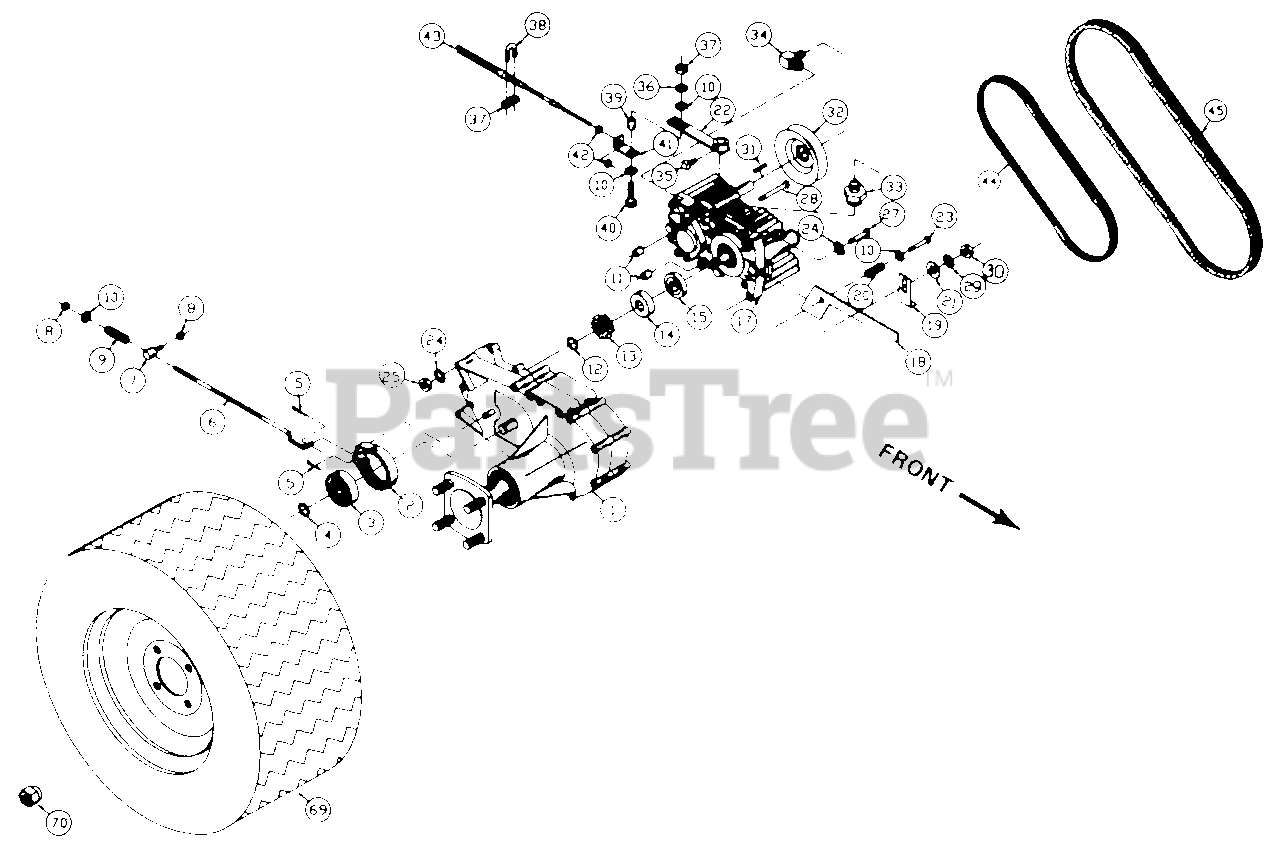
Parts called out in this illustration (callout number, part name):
1	ZT Transmission
5	Coteer Pin, 1/8" x 1"
6	Brake Linkage Rod
7	Caliper Rod Collar
8	Elastlc Stop Nut, 1/4-20
10	Flatwasher, 1/4"
12	Snap Ring
14	Bearing
17	Sundstrand Pump, RH
18	Transmission Dump Lever
19	Transmission Dump Lever Stop
20	Compression Spring, 9/16" OD x 1 3/8"
21	Flatwasher, 3/8"
22	Transmission Arm
23	Dump Valve Bolt
24	Lockwasher, 5/16"
25	Hex Nut, 5/16-18
27	Hex Bolt, 5/16-18 x 2", GRS
28	Hex Bolt, 5/16-18 x 7 1/2", GRS
29	Lockwasher, 3/8"
30	Hex Nut, 3/8-16
31	Key, 5 x 5 x 25mm
32	Pulley, 4" OD x l5mn ID
33	Male Tube, Male O-ring Adapter
34	Male Tube, 90ø Male O-ring Adpt.
35	Squarehead Setscrew, 5/16-L8 x 1/2"
36	Lockwasher, 1/4"
37	Hex Nue, 1/4-20
38	Steering Cable Clamp
39	Steering Cable Bushing
40	Hex Bolt, 1/4-20 x 1", GRS
41	Steerlng Cable Ent
42	Hex Nut w/Star Washer, 10-32
43	Steerlng Cable, 3/16" x 58"
44	Pump Drlve Belt
45	Belt
69	Drive Wheel Assembly
70	Lug Nut, 1/2-20
